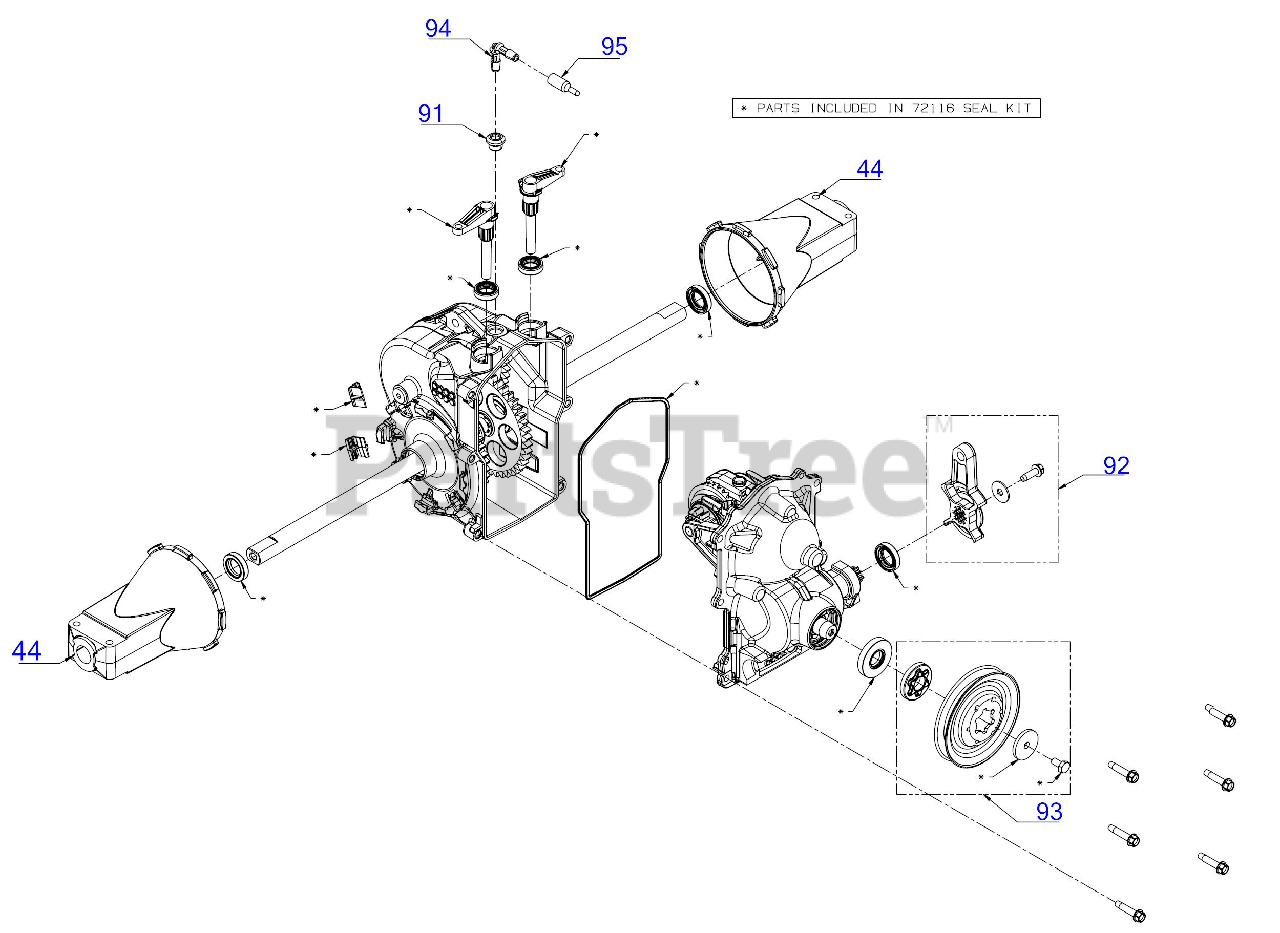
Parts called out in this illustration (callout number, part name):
44	AXLE HORN
91	FITTING GROMMET
93	PULLEY KIT
94	ELBOW FITTING
95	FITTING CAP
